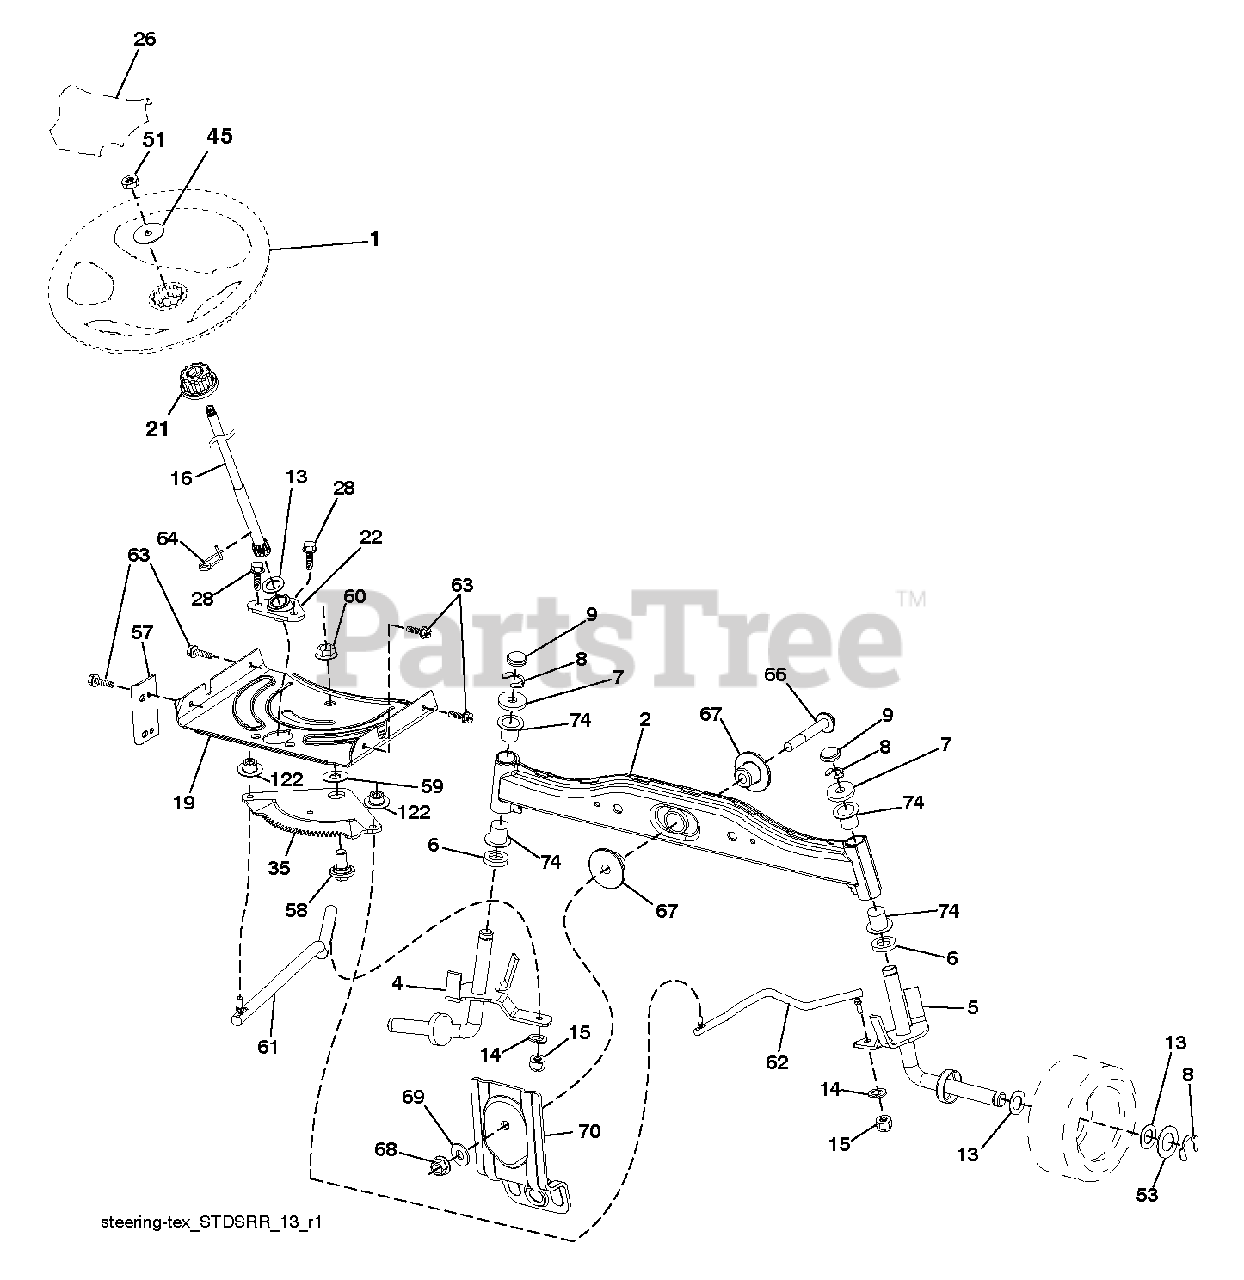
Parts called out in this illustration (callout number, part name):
1	WHEEL.STEERING.HUSQ.PREM.HRDRM
2	AXLE HALF ASM-WELDED
4	SPINDLE.WELDED.LH.15"TEX
5	SPINDLE.WELDED.RH.15"T
6	THRUST WASHER
9	CAP.SPINDLE.BLACK
14	WASHER, LOCK 3/8
15	NUT CROWNLOCK 3/8-24
16	SHAFT.STEER.STEALTH.DD
19	PLATE.STEER.DDL.NLT/NG
21	ADAPTER, WHEEL STNG..
22	STEERING.SUPT.LOWER.
26	INSERT.CAP.WHL.STRG.HUSQ.PREM
28	SCREW, 3/8-16X3/4
35	GEAR.SECTOR.PLATE.DDL.
45	WASHER 9/16"ID, 2 3/8"OD
51	NUT.HEX.1/2-20
53	WASHER.HARDENED
57	BRACKET.UPSTOP.TEX
58	BOLT.SHOULDER.SECTOR.P
59	WASHER.THURST.SECTOR.S
60	NUT FLANGE LOCK 5/8-11
61	DRAGLINK.LH.BALLSTUD.D
62	DRAGLINK.RH.BALLSTUD.D
63	SCREW
64	RETAINER.CLIP.SPRING.S
66	BOLT HEX FGHD 7/16-14 X 3 SERR
67	BUSHING.PM.FRONT AXLE
68	NUT.LOCK.FLANGE.7/16
69	WASHER.1.5X.505X.118
70	BRACKET.FRT.DECK.SUSP.RR.MT431
74	BRNG T
122	CAP.GEAR.SECTOR.TEX
